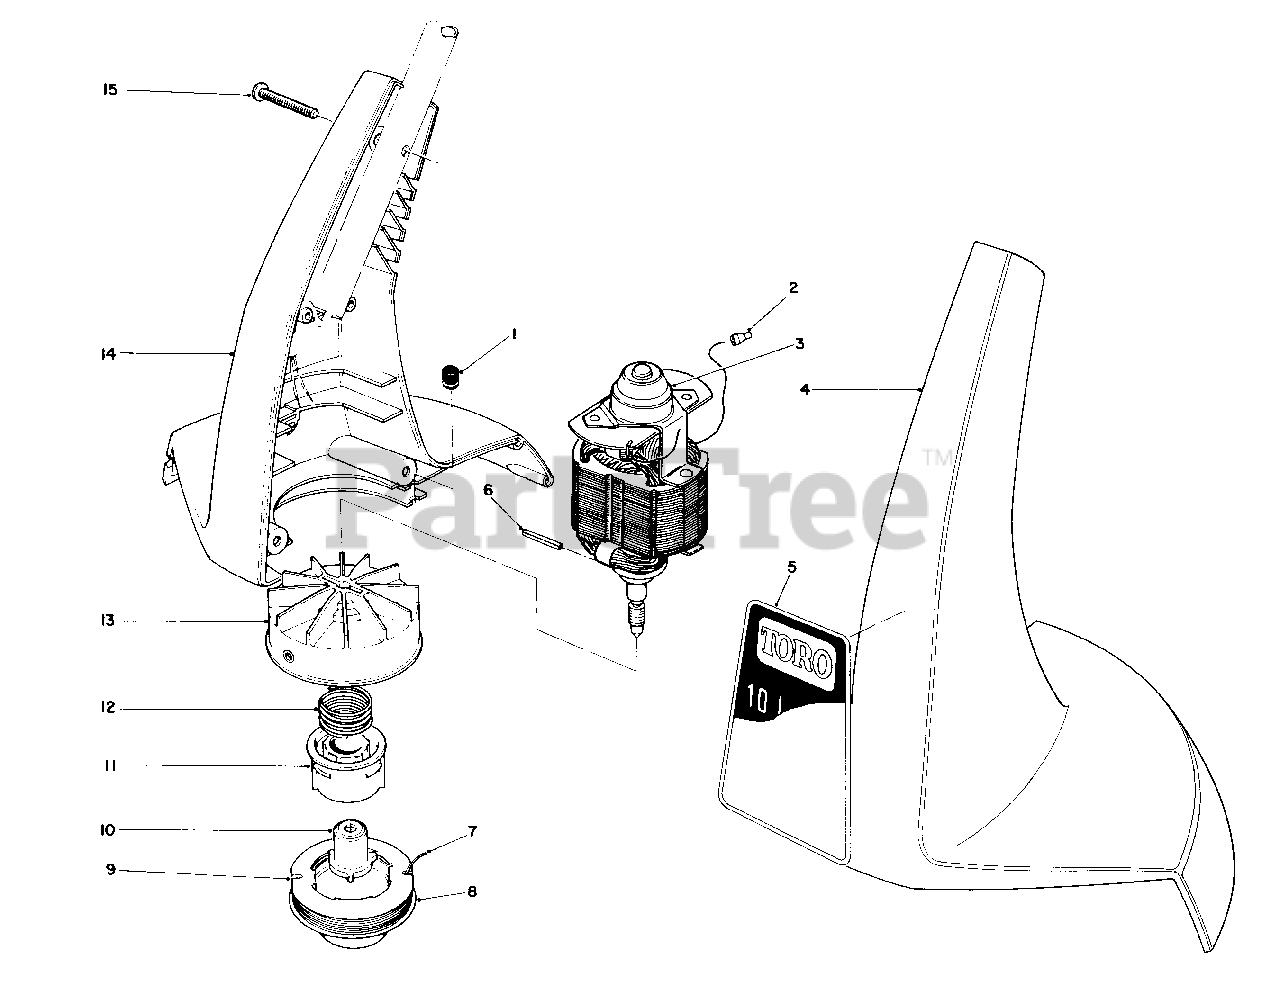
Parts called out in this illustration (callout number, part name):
2	Connector-Electric
4	Housing-L.H.
5	Decal-Housing
7	Line-Cutting(30' .05 Dia.) Prewound on Spool
8	Cap-Spool
9	Line-Cutting (30' .05 Dia)
10	Driver-Detent
11	Core-Spool
12	Spring-Compression
13	Fan Hub Assembly
14	Housing Assembly-R.H. (Incl. Ref. #16 & 17)
15	121 Screw-Thread Forming
